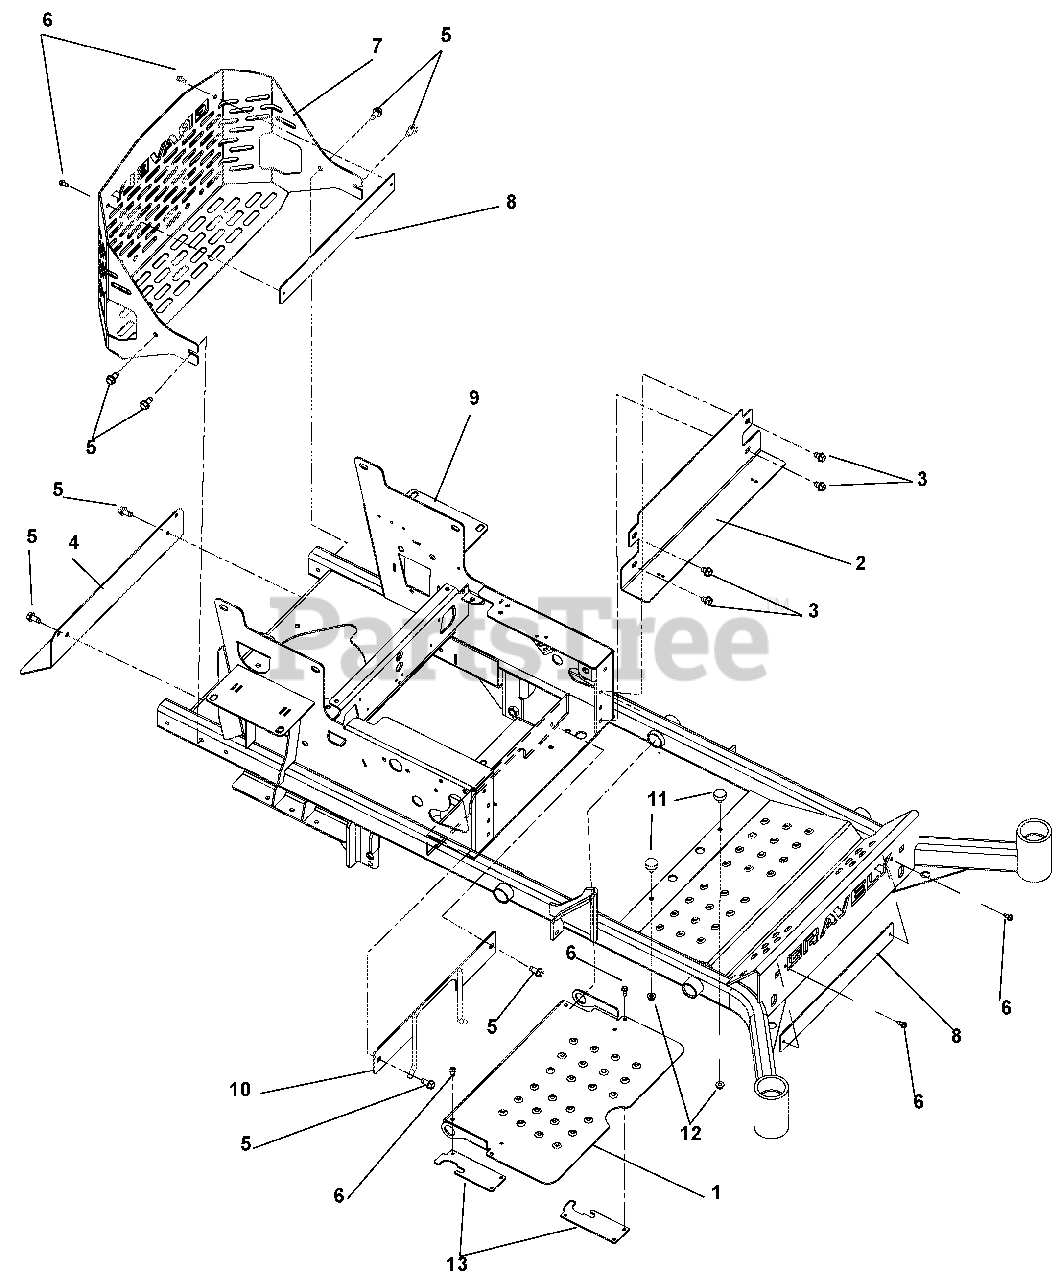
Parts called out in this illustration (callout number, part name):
1	Foot Plate
2	Kick Plate
3	Screw, Tapping .38-16 x .50 Hex Washer Head Thread Rolling
4	Muffler Heat Shield
5	Screw, Tapping .38-16 x .75 Hex Washer Head
6	Screw, Tapping .25-20 x .50 Hex Washer Head
7	Pro-Turn 100 Bumper
8	Bumper Plate
9	Frame, Pro-Turn 100 48"
10	PTO Belt Finger Weldment
11	Bumper, Rubber
12	Nut, Spin Lock-Flange .312-18
13	Pro-Turn 100CE Foot Plate Finger Cover
